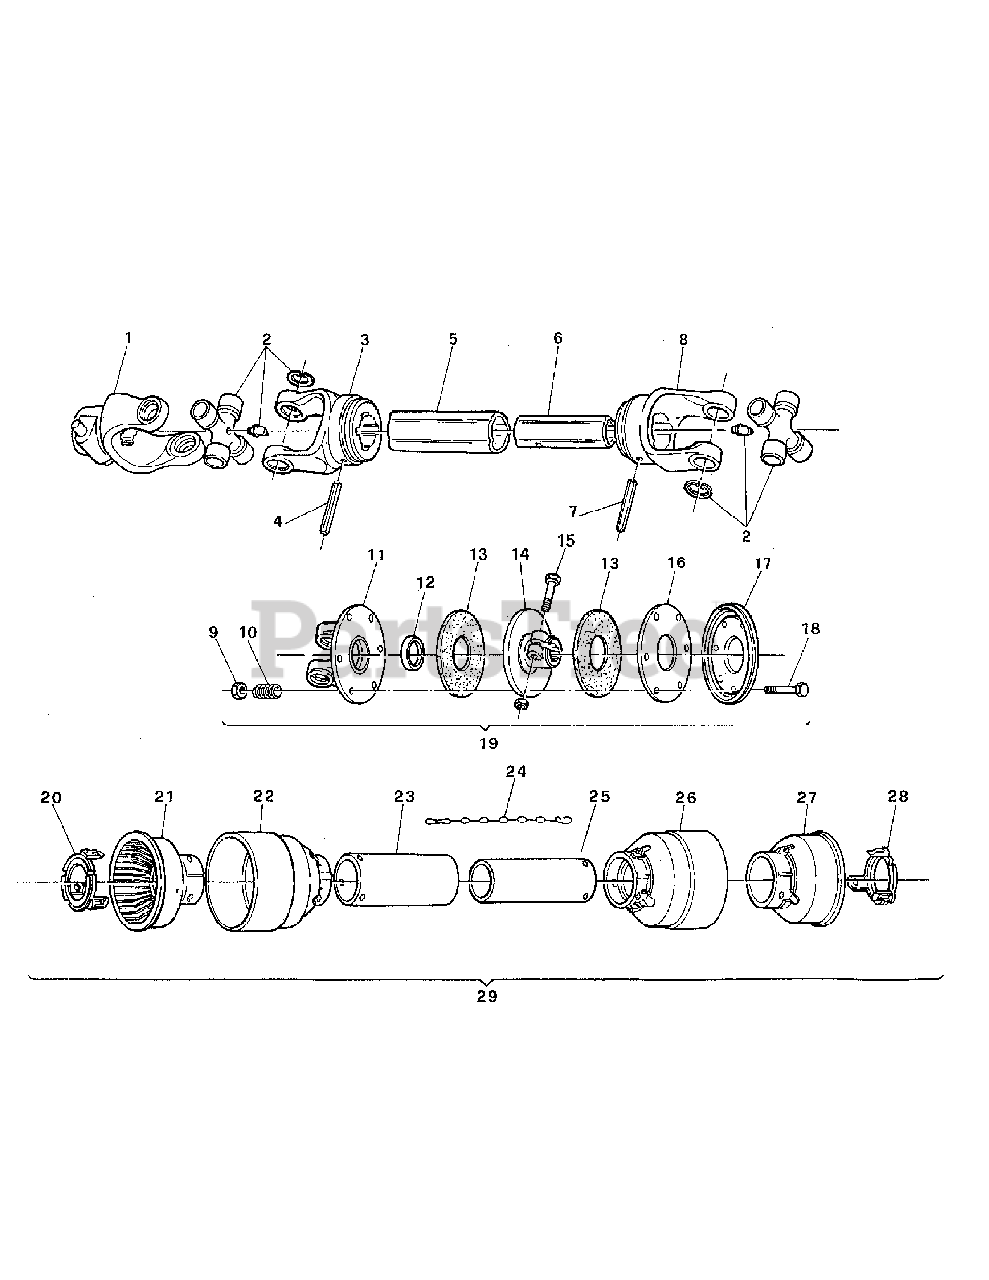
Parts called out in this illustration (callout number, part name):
1	PTO yoke
2	Cross & bearing
3	Female yoke
4	Roll pin Ø10x80
5	Female shaft
6	Male shaft
7	Roll pin Ø10x70
8	Male Yoke
9	Locking nut M10
10	Spring
11	Yoke slip clutch
12	Bushing
13	Friction disc
14	Body slip clutch
15	Bolt and nut M12x70
16	Outer flange
17	Outer cone
18	Hex bolt M10x80
19	Complete slip clutch
20	Outer tube locking ring
21	Outer tube rigid cone
22	Outer cone
23	Female tube shield
24	Chain
25	Male tube shield
26	Inner cone
27	Inner tube rigid cone
28	Inner locking ring
29	Complete shielding
